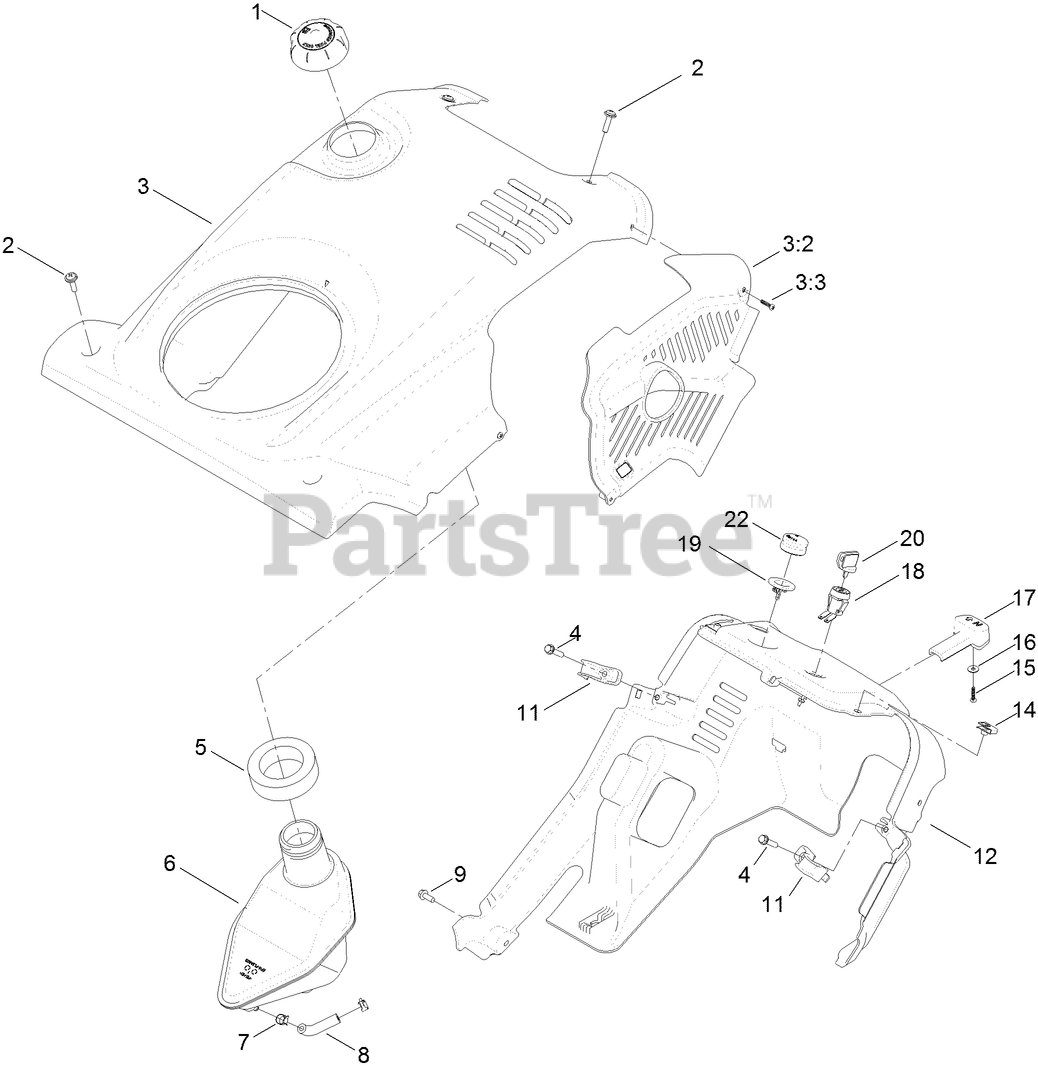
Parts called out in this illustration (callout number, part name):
2	SCREW-PPH
3	SHROUD ASM
3:2	BAFFLE-EXHAUST
3:3	SCREW-PPH
4	SCREW-PLASTITE
5	SEAL-TANK
6	TANK-FUEL, GAS
7	CLAMP-HOSE
8	HOSE-FUEL
9	SCREW-HWH
11	CLIP-SHROUD
12	SHROUD-LOWER
15	SCREW-PPH
16	WASHER-PLAIN
17	KNOB-CHOKE
18	SWITCH
19	BODY-PRIMER
20	KEY-IGNITION
22	BULB-PRIMER
